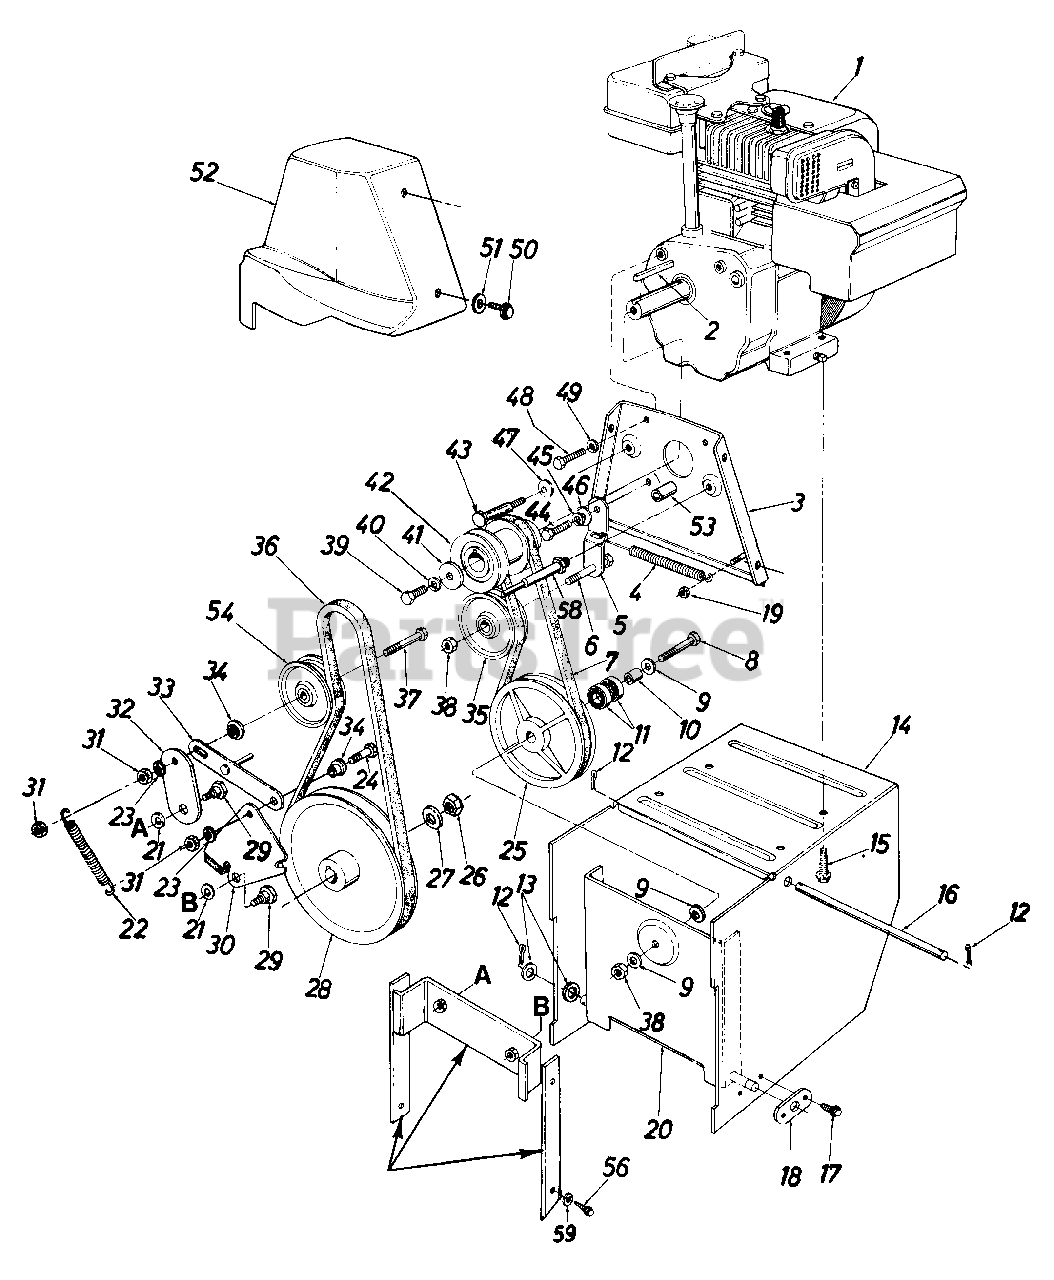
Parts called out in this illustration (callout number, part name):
1	Engine
2	Sq. Key 3/16" x 1.50" Lg.
3	Engine Plate Ass'y.
4	Extension Spring .50" O.D. x 3.97" Lg.
5	Drive Clutch Idler Brkt.
6	Hex Bolt 3/8-24 x 1.25" Lg.*
7	"V"-Belt
8	Hex Bolt 3/8-24 x 1.50" Lg.
9	Bell-Wash. .40" I.D. x .88" O.D. x .06
10	Spacer 38" I.D. x .62" O.D. x.75" Lg.
11	Ball Brg. .62" I.D. x 1.38" O.D. x .44
12	Cotter Pin 3/32" Dia. x .75" Lg.
13	Fl-Wash. .53" I.D. x 1.00" O.D. x .125
14	Frame Ass'y.
15	Hex Wash. Hd. Self-Tap Scr. 3/8-16 x 1.25" Lg.
16	Shaft .50" Dia. x 9.50" Lg.
17	Hex Wash. Hd. Self-Tap Scr. 1/4-20 x .50" Lg.
18	Axle Bracket
19	Hex L-Nut 1/4-20 Thd.
20	Drive Pulley Support Brkt. Ass'y.
21	Bell-Wash. .40" I.D. x 1.13" O.D.
22	Extension Spring .56" O.D. x 4" Lg.
23	L-Wash. 3/8" I.D.
24	Hex Scr. 3/8-16 x 1.25" Lg.
25	6.00" O.D. Drive Pulley Ass'y.
26	Hex Jam Cent. L-Nut 5/8-18 Thd.
27	Fl-Wash. .64" I.D. x .94" O.D. x .06
28	1/2" V-Pulley .625" I.D. x 7.50" O.D.
29	Shld. Bolt .625" Dia. x .170" Lg. (3/8-16)
30	Brake Bracket Ass'y.
31	Hex Ins. L-Nut 3/8-16 Thd.
32	Auger Clutch Idler Brkt.
33	Brake Linkage Ass'y.
34	Shld. Spacer.625" I.D.
35	Fl-Idler Pulley 2.25" O.D.
36	"V"-Belt
37	Hex Bolt 3/8-16 x 2" Lg.
38	Hex Ins. Jam L-Nut 3/8-24 Thd.
39	Hex Bolt 3/8-24 x 1.50" Lg.
40	L-Wash. 3/8" I.D.
41	Bell-Wash. .40" I.D. x 1.25" O.D.
42	Double Groove Engine Pulley
43	Shld. Scr. .498" x 3.0" Lg.
44	Hex Bolt 5/16-24 x 1.00" Lg.
45	L-Wash. 5/16" I.D.
46	Shld. Spacer.27" Lg.
47	Bell-Wash. .40" I.D. x .88" x .06
48	Hex Bolt 5/16-24 x .62" Lg.
49	L-Wash. 5/16" I.D.
50	Hex Wash. Hd. Self-Tap Scr. 1/4-20 x .50 Lg.
51	Fl-Wash. .28" I.D. x .75" O.D. x .06
52	Belt Cover
53	Spacer
54	Fl-Idler Pulley 2.75" O.D.
56	Hex Wash. Hd. Self-Tap Scr. 3/8-16 x .75" Lg.
58	Stud 3/8-16 x 3.37" Lg.
59	L-Wash. 3/8" I.D.-H.D.
